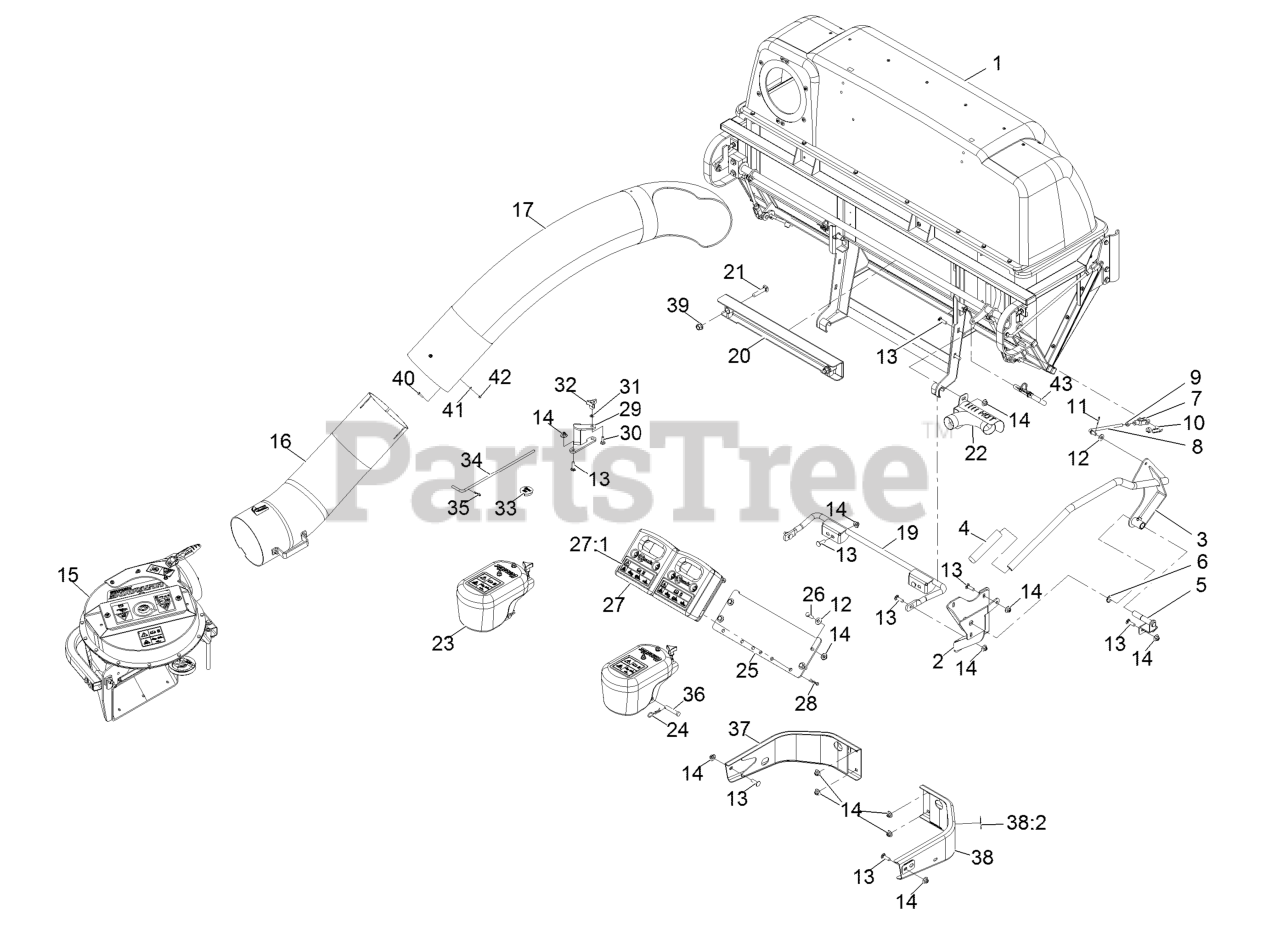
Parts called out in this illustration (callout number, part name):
1	ASM,Hopper Lg Qds
2	Mount-Pivot
3	Wld,Dump Handle
4	Handle-Grip
5	Pin-Handle
7	Yoke-Linkage, Brake
8	Link-Handle
9	Nut-Hex 3/8-24
10	Pin-Clevis Spring 3/8
11	Pin-Cotter 1/8 X 3/4
12	Washer-3/8 Std
13	Bolt-Carriage 3/8-16 X 1 1/4
14	Nut-Nyloc 3/8-16 Flg
15	ASM, Blower Large - Svc Only
16	Lower Tube ASM
17	Tube-Upper
19	Mount-Bagger, Lower
20	Mount-Bagger, Upper
21	Bolt-Carriage 1/2-13 X 2 1/2
22	Exhaust Diverter ASM
23	ASM,Caster Weight
24	Hairpin-Cotter
25	Plate, Weight Mounting
26	Screw-HH 3/8-16 X 1 1/4
27	Asm, Weight (103-6364-01) W/Decals
27:1	Decal-Warning Weight
28	Hairpin-Cotter
29	Bracket,Belt Cover
30	Bolt-Carriage 5/16-18 X 1
31	Ring-Bolt Retaining
32	Knob-3 Prong
34	Pin, Chute Pivot
35	Hairpin-Cotter
36	Pin-Clevis
37	Bumper-RH
38	LH Bumper ASM
38:2	Decal-Warning
39	Nut-Lock 1/2-13
40	Screw-HWH #10-24 X 3/4
41	Washer-#10 Std
42	Nut-Nyloc #10-24
43	Pin-Mount, Bagger
